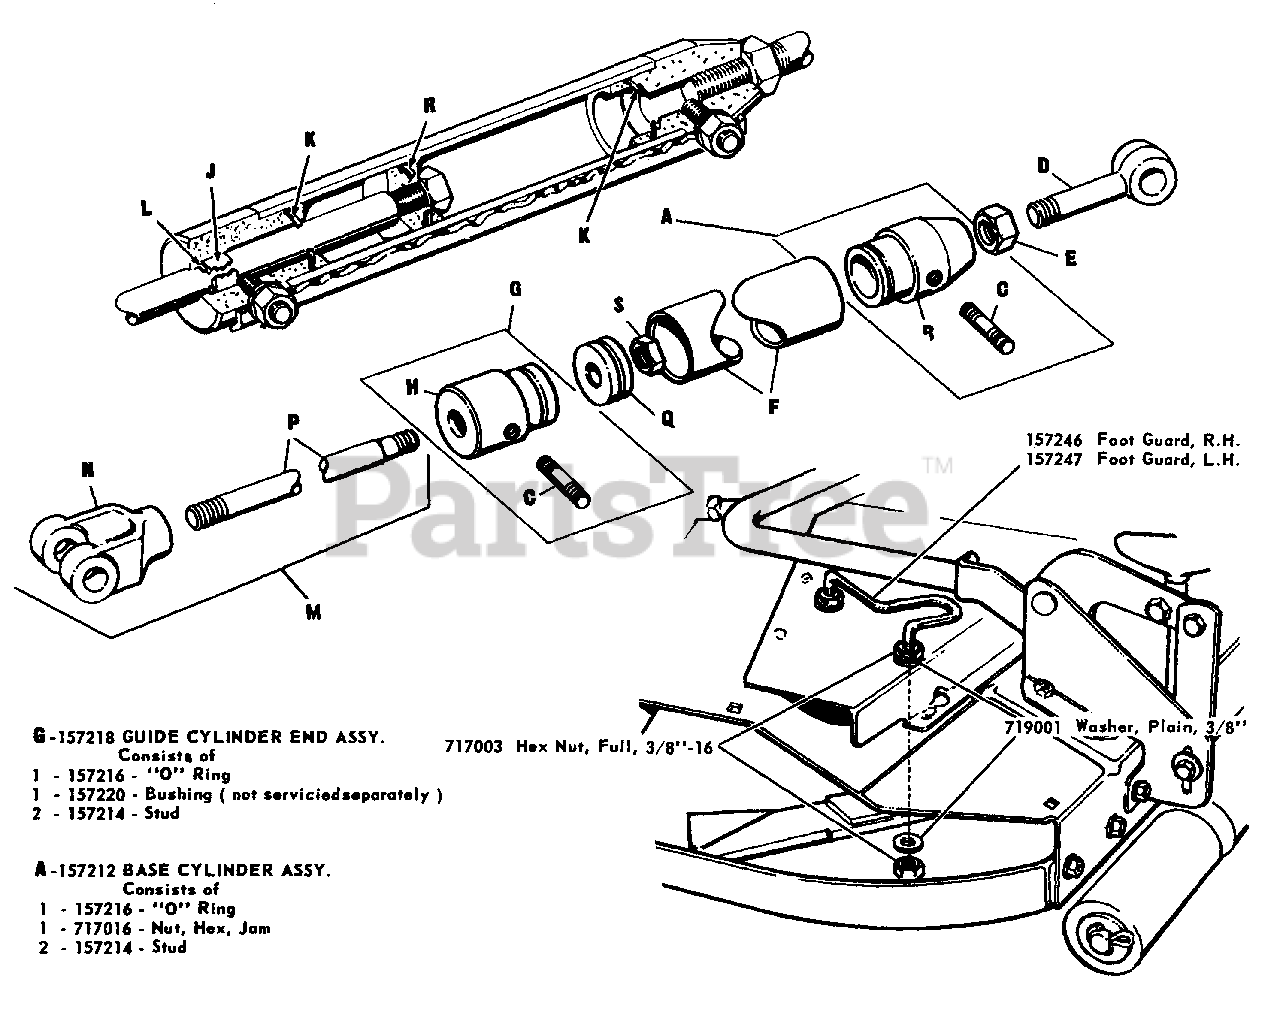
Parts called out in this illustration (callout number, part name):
A	Cylinder Base Sub-Assembly
B	Cylinder Base
C	Stud Bolt, 5/16"-18 x 7/8"
E	Jam Hex. Nut, 1/2"-20
G	Sub Assembly Guide
H	Cylinder End Guide
M	Yoke & Rod Sub-Assembly
P	Piston Rod
S	Full Hex. Nut
